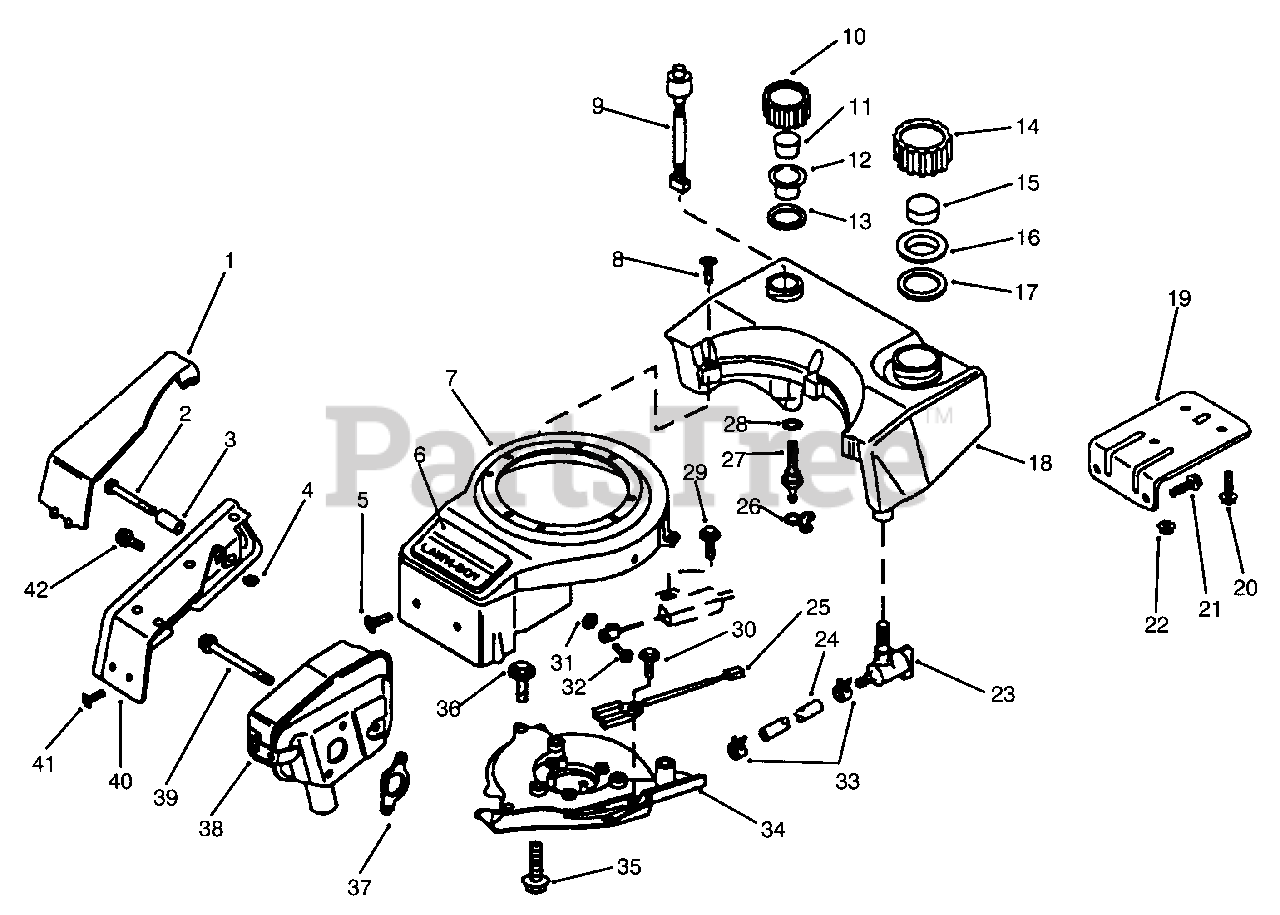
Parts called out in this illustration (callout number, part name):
1	Cover-Muffler
2	Screw-Muffler Guard
3	Spacer-Muffler Guard
4	Pushnut
5	Screw-Shroud
6	Applique
7	Assembly-Shroud (Incl. Ref. No. 6)
8	Screw-Fuel Tank
9	Switch-Low Oil
10	Assembly-Oil Cap (Incl. Ref. No. 11-13)
12	Cover-Baffle
14	Fuel Cap Assembly (Incl. Ref. No. 15-17)
16	Cover-Baffle
18	Tank-Fuel/Oil (Incl. Ref. No. 9,23 & 27-28
19	Bracket-Fuel Tank
21	Screw-Tank Bracket/Block
22	Screw-Mtg. Plate/Engine
23	Shut-Off Valve-Fuel
24	Fuel Line
25	Switch-Brake Interlock
26	Clamp-Oil Hose
27	Assembly-Oil Fitting (Incl. Ref. No. 28)
30	Screw-Interlock Switch
33	Clamp-Fuel Line
34	Plate-Engine Mounting
35	Screw-Mtg. Plate/housing
36	Screw-Mtg Plate/Housing
37	Gasket-Exhaust
38	Muffler
39	Screw-Muffler
40	Assembly-Muffler Guard (Incl. Ref. No. 1 & 4)
41	Screw-Muffler Guard
42	Screw-Muffler Guard
